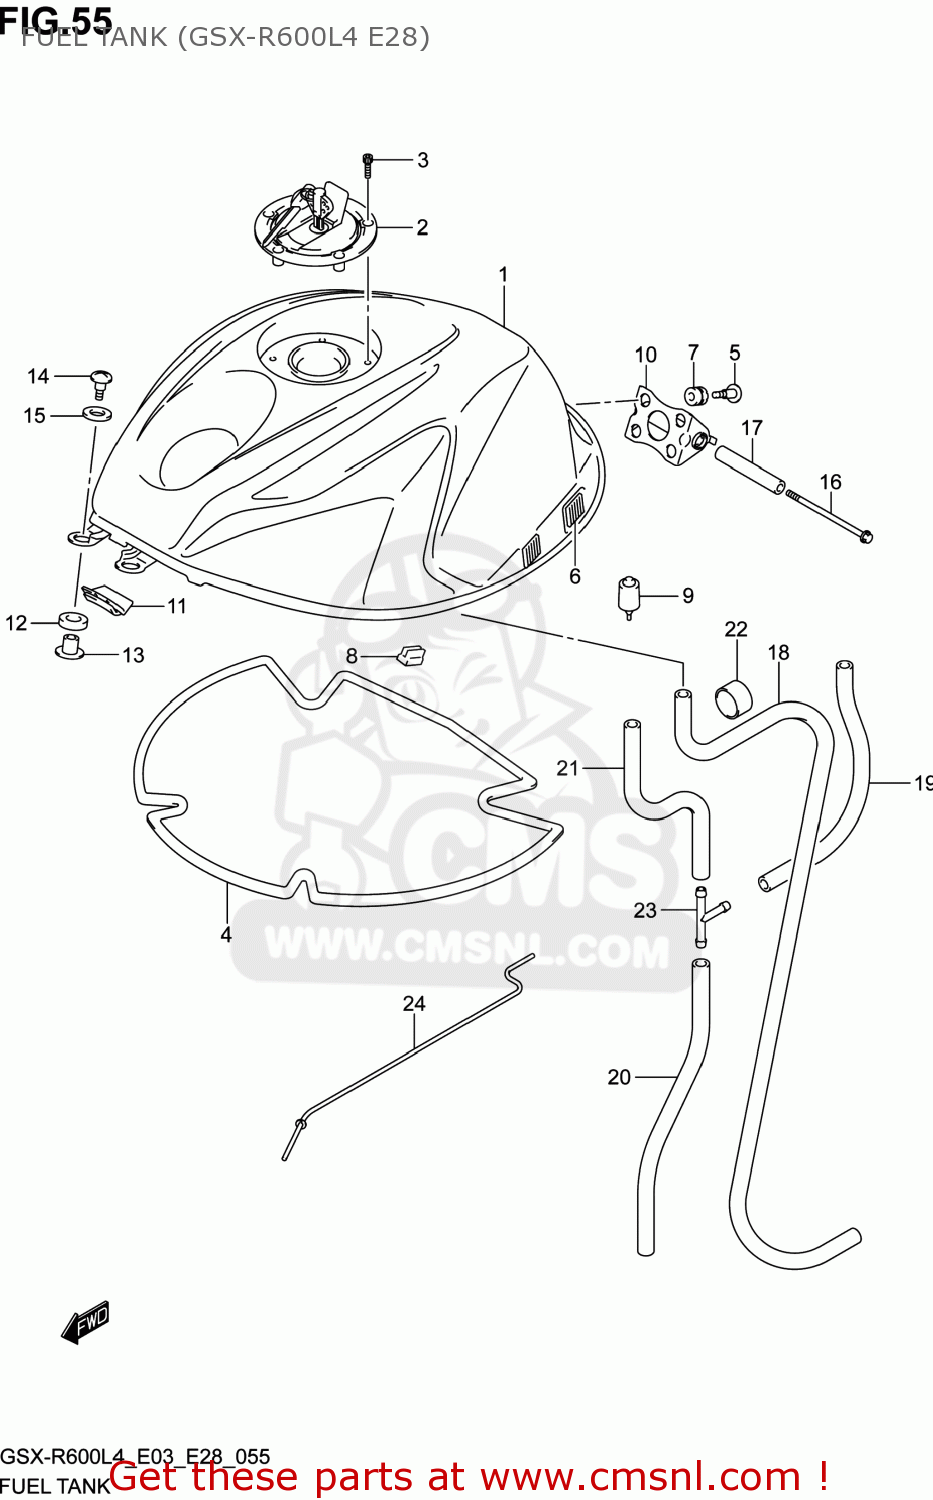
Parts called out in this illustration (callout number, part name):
1	TANK ASSY,FUEL(BLUE)
2	CAP SET,FUEL TANK
3	BOLT(5X20)
4	SHIELD,FUEL TANK HEAT
5	SCREW,FUEL TANK RR BRACKET
6	FASTENER
7	CUSHION
8	CUSHION,FUEL TANK COVER
9	CUSHION,FUEL TANK RR
10	BRACKET,FUEL TANK NO.1
11	RUBBER,FUEL TANK FR
12	CUSHION,FUEL TANK FR
13	SPACER,FUEL TANK FR
14	SCREW(6X25)
15	WASHER(6,5X22X1.6)
16	BOLT(6X110)
17	SPACER,FUEL TANK RR
18	HOSE,FUEL TANK WATER DRAIN
19	HOSE,FUEL TANK BREATHER NO.1
20	HOSE,FUEL TANK BREATHER NO.2
21	HOSE,VACUUM
22	HOSE(12X16X600)
23	3 WAY
24	STAY,FUEL TANK
